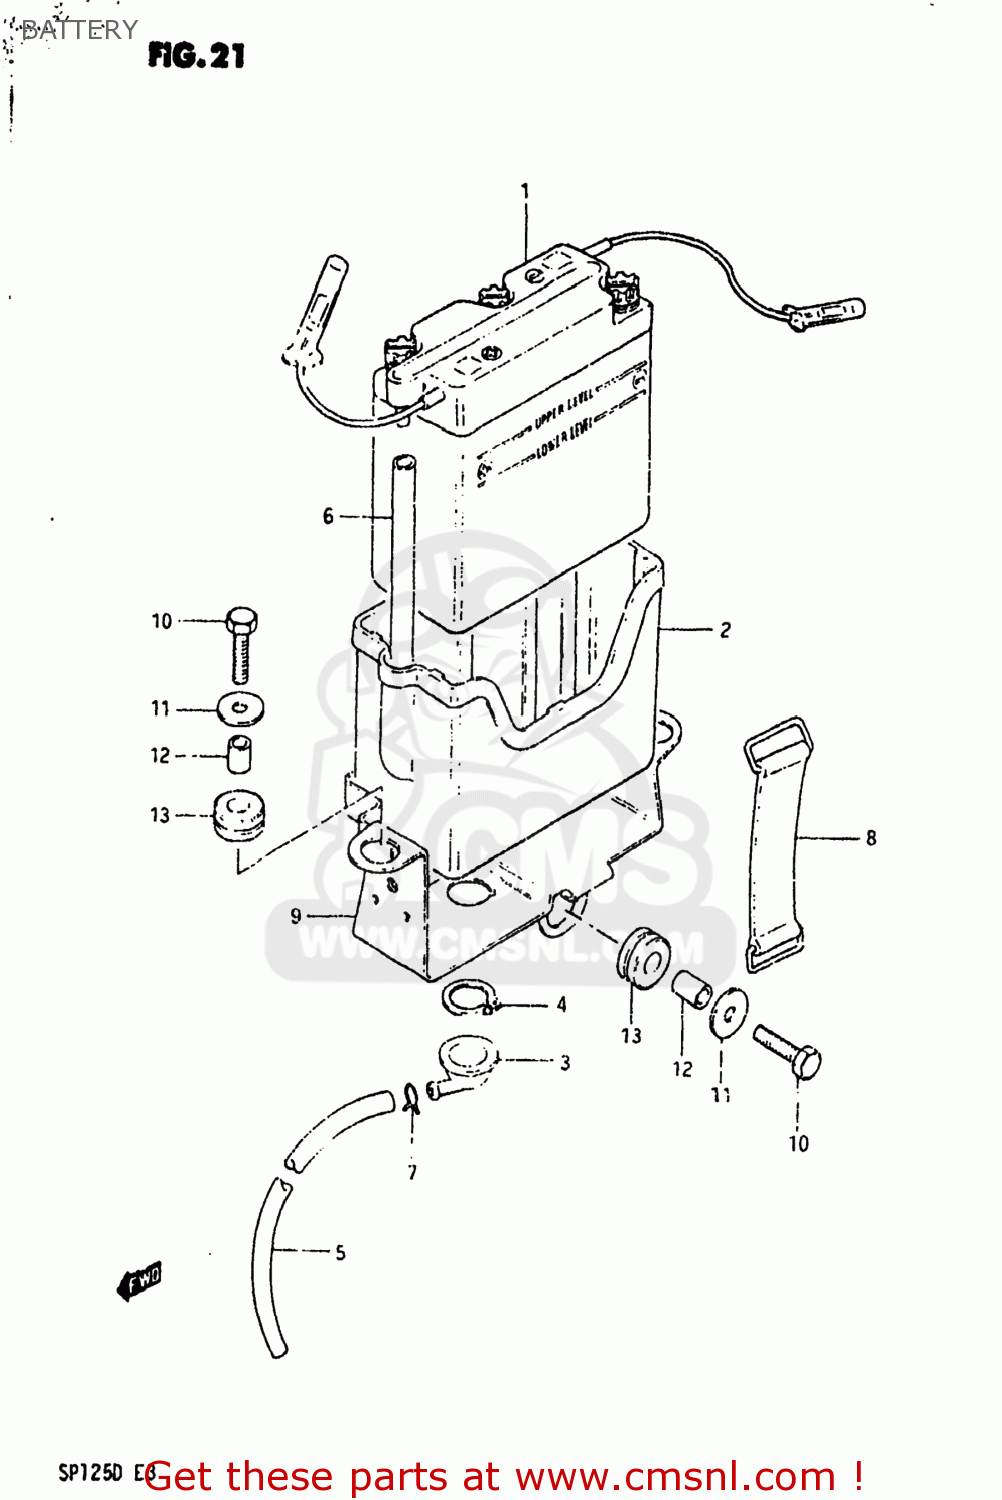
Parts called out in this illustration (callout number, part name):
1	BATTERY ASSEMBLY
2	CASE,BATTERY
3	FUNNEL,BATTERY EXHAUST
4	CIRCLIP
5	HOSE,BATTERY EXHAUST
6	HOSE, EXHAUST (L:45)
7	CLIP
8	BAND
9	HOLDER,BATTERY
10	BOLT, UPPER
11	WASHER (6.5X20X1.2)
12	SPACER(6.1X9X7.5)
13	CUSHION
